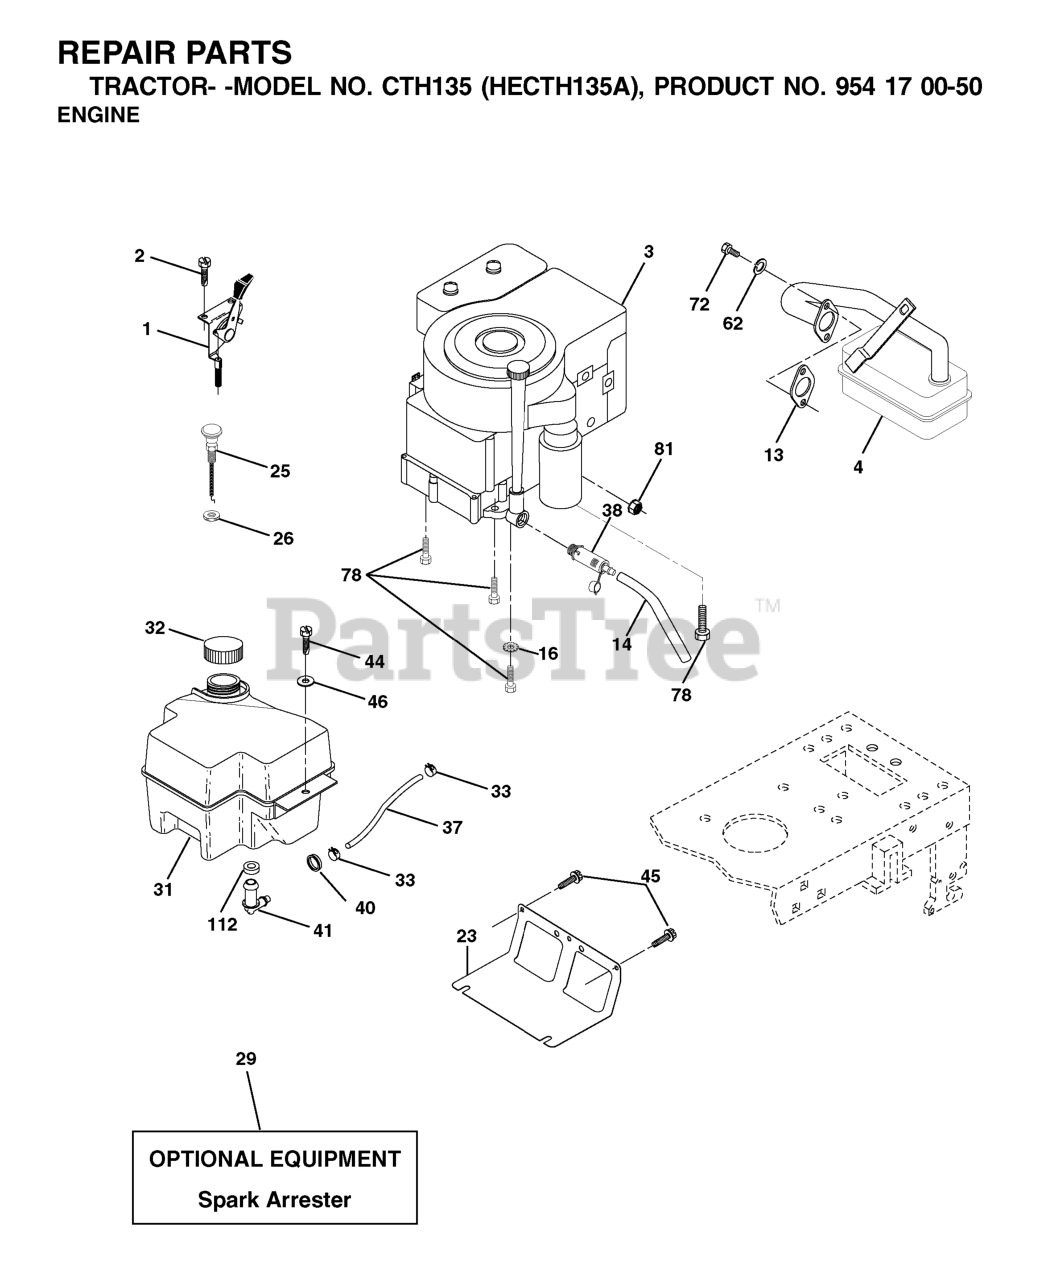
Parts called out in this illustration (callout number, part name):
1	CONTROL.THROTTLE/CHOKE.BLACK
2	SCREW
4	MUFFLER.LT.BRIGGS.14HP.IC/OHV
4	MUFFLER.B&S.MODEL.21.11HP.OHV
13	REPL BY 532 27 22-93
14	TUBE, DRAIN OIL ASM.
16	LOCKWASHER
23	SHIELD.BROWNING.DBR.GUARD
26	Nut Keps 3/8 - 24 UNF
29	KIT.SPARK ARRESTOR 794945 B&S
31	GAS TANK 2GAL
32	FUEL CAP
33	HOSE CLAMP
37	LINE.FUEL.20
38	PLUG, OIL DRAIN EASY
40	BUSHING.SNAP.NYL.BLK.
41	STEM FUEL TANK
44	SCREW HEXWSHR 1/4-20X3/4
45	SCREW, 3/8-16X3/4
62	WASHER.LOCK.HVY.HLCL.SPR.5/16
72	SCREW
78	SCREW.3/8-16
81	NUT
112	BUSHING OUTLET T
